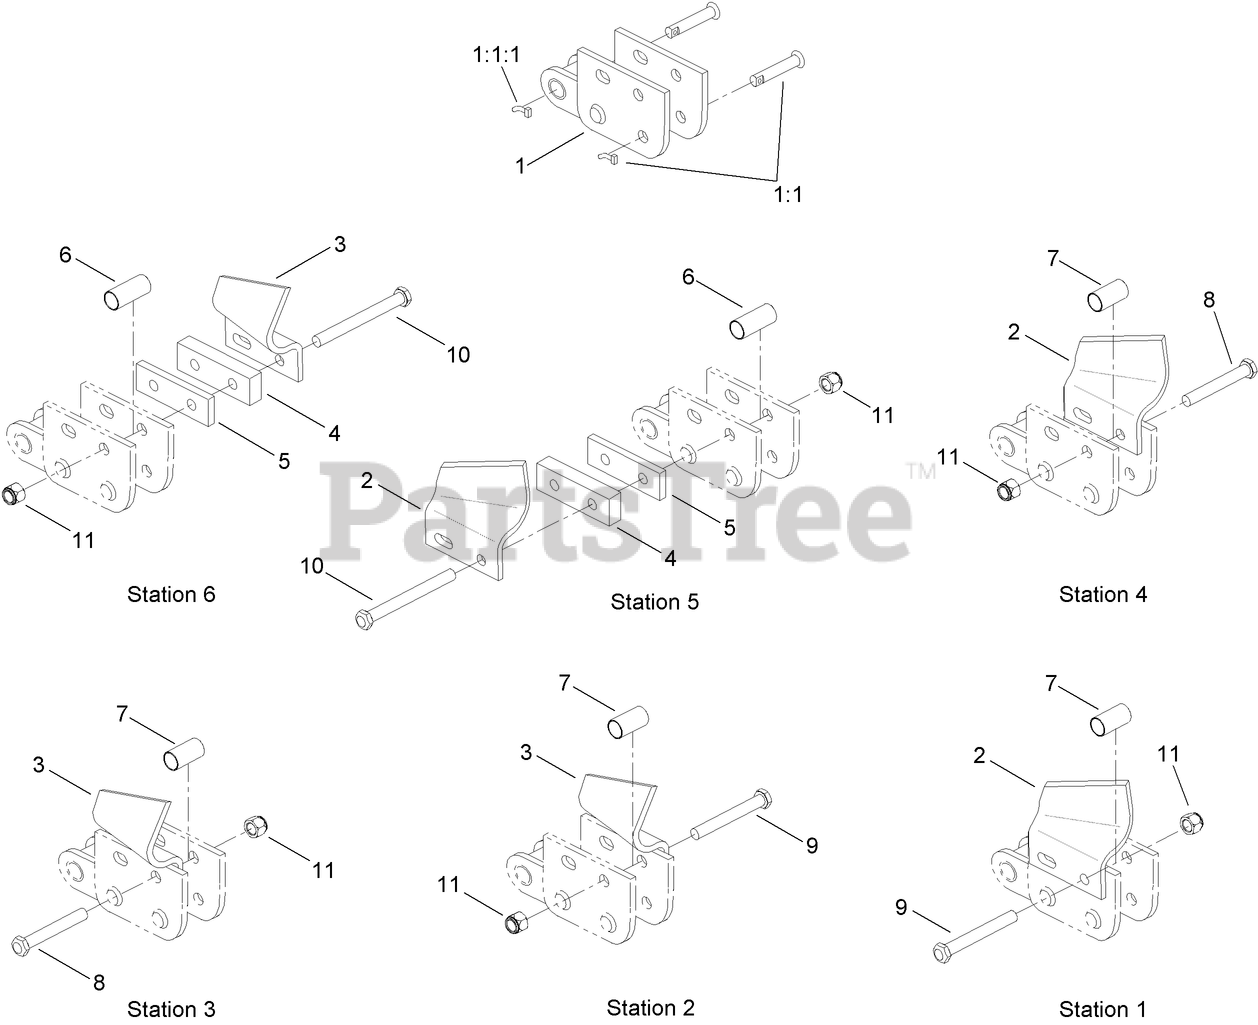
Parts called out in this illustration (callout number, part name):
1	CHAIN REPAIR LINK ASM
1:1	NOTCHED PIN AND KEEPER ASM
1:1:1	PIN-KEEPER
2	CUTTER-CUP, LH
3	CUTTER-CUP, RH
4	SPACER-FLAT (.500 Inch)
5	SPACER-FLAT (.250 INCH)
6	SPACER-TUBE, OUTSIDE MOUNT
7	SPACER-TUBE, INSIDE CUP MOUNT
8	BOLT-HH
9	BOLT-HH
10	BOLT-HH
11	NUT-LOCK
